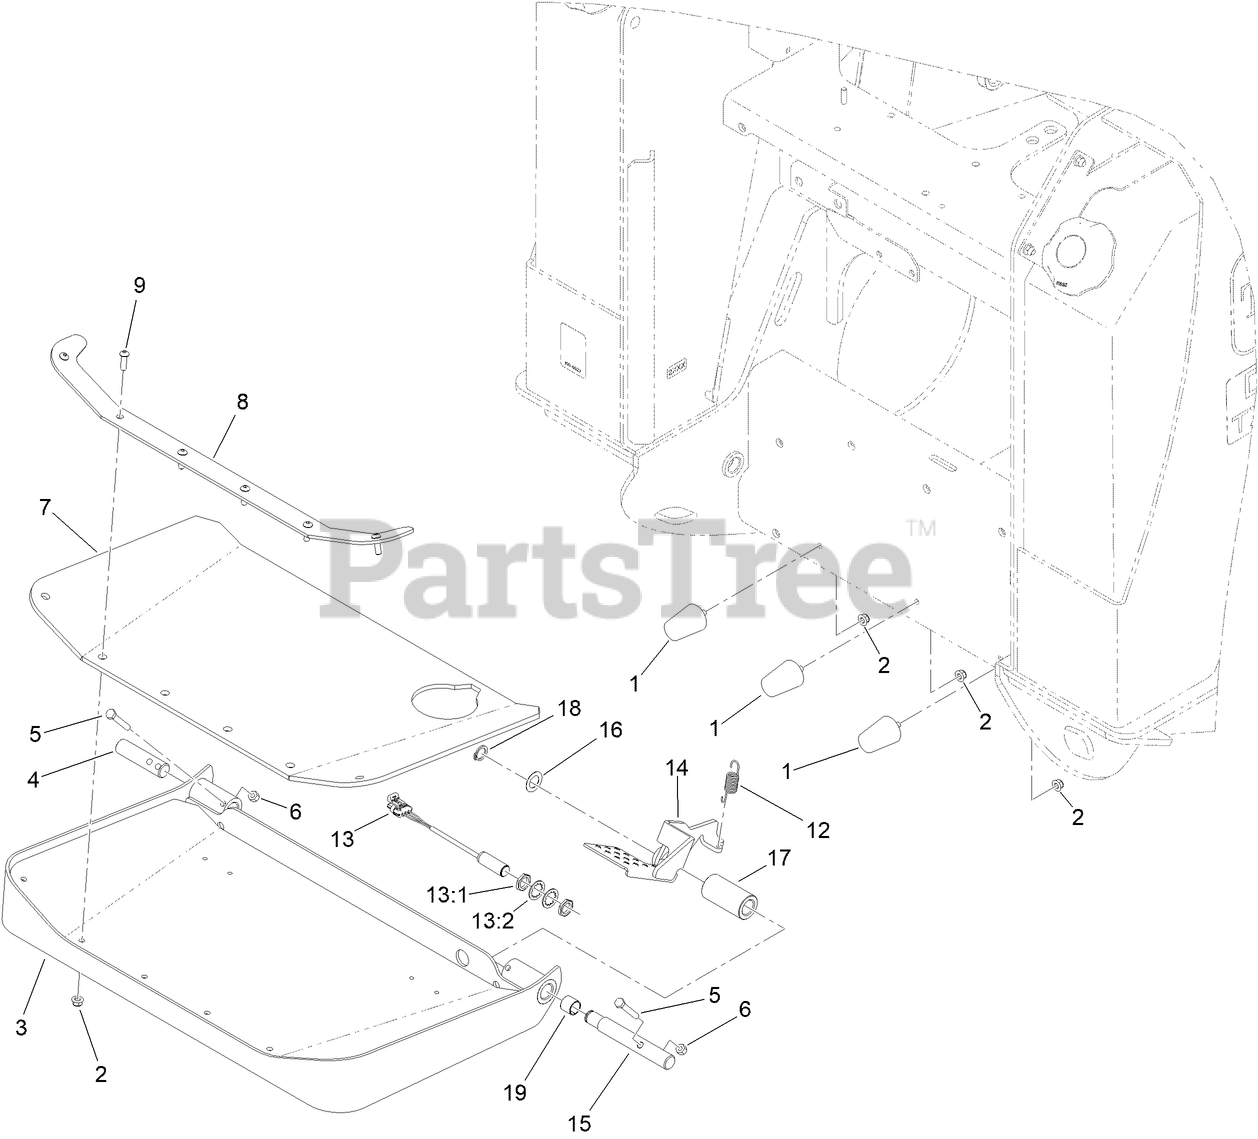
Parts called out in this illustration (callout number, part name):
1	BUMPER
2	NUT-HF, NI
3	PLATFORM
4	PIN-PIVOT
5	SCREW-HH
6	NUT-LOCK, NI
7	PAD-PLATFORM
8	BRACKET-CLAMP, PLATFORM
9	SCREW-HSBH
12	SPRING-EXTENSION
13	PROXIMITY SWITCH ASM
13:1	NUT-HEX
13:2	WASHER-LOCK, INTERNAL TOOTH
14	PEDAL ASM, [BLACK]
15	PIN-PIVOT
16	WASHER-FLAT
17	SPACER
18	RING-RETAINING
19	BUSHING-STRAIGHT
